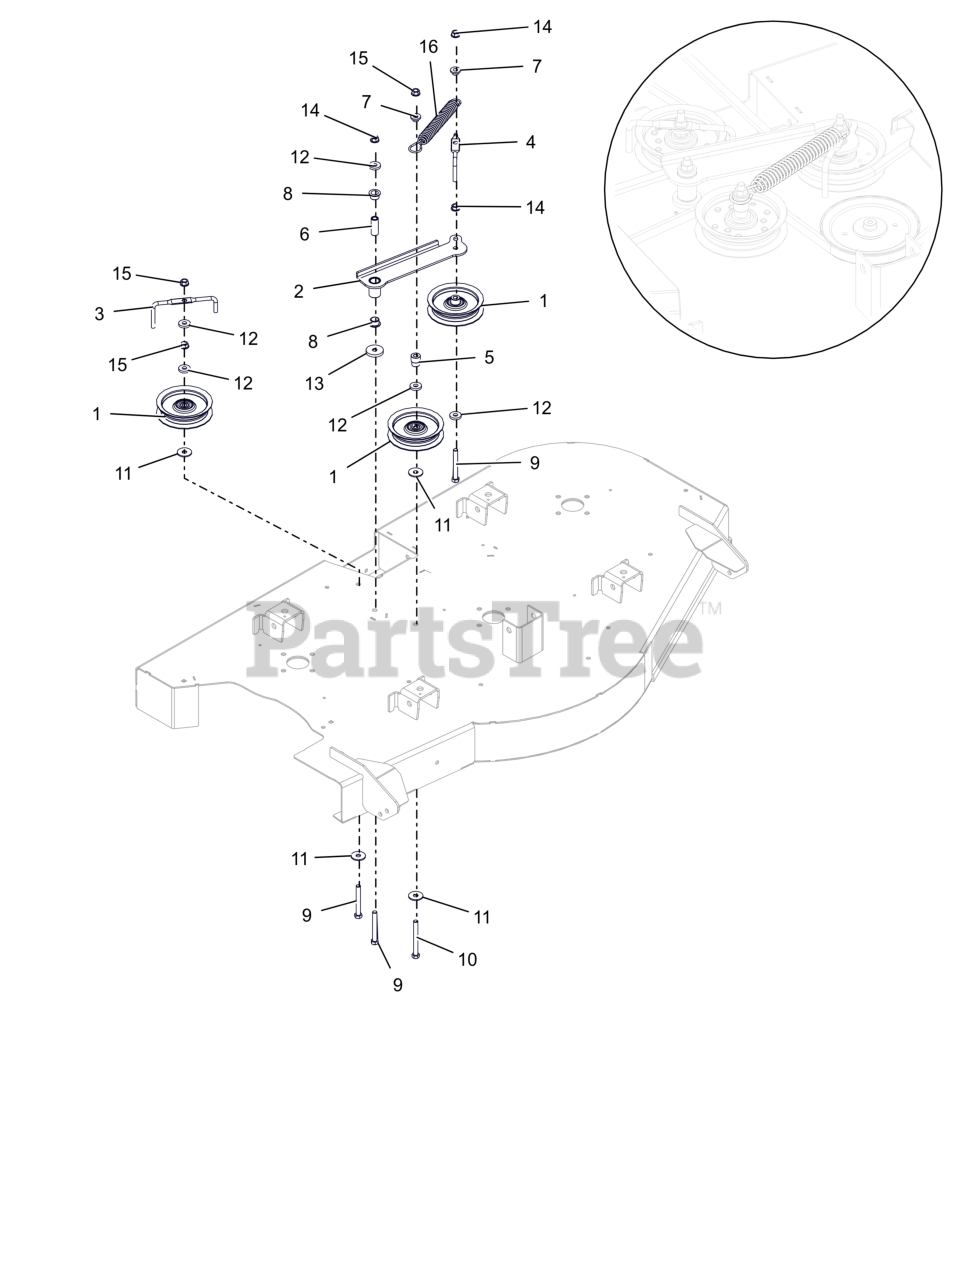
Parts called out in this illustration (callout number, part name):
1	IDLER, FLAT - 4.06" X .75"
2	WLDMT, IDLER ARM-52"
3	BELT FINGER
4	WIREFORM, BELT FINGER
5	BUSHING, IDLER (P/M)
6	SPACER, .375IDX.625ODX1.66 PM
7	BSHG-FLG .385X.500X.875X.406
8	BSHG-FLG, .625X.750X.500X1.00
9	BLT, HEX .38-16X3.00F G5 ZCC
10	BLT, HEX .38-16X3.50 G5 ZCC
11	WSHR FL STL .406X1.25X.10ZC120
12	WSHR, FLT .406X1.00X.188 ZCC
13	WSHR, FLT .406X1.50X.245 ZCC
14	NUT-LK-CTR-FLG .375-16 GF ZCC
15	NUT-LK-CTR-FLG .375-16 GF ZCC
16	SG-TENS .135X.98X6.0 WLD 62
